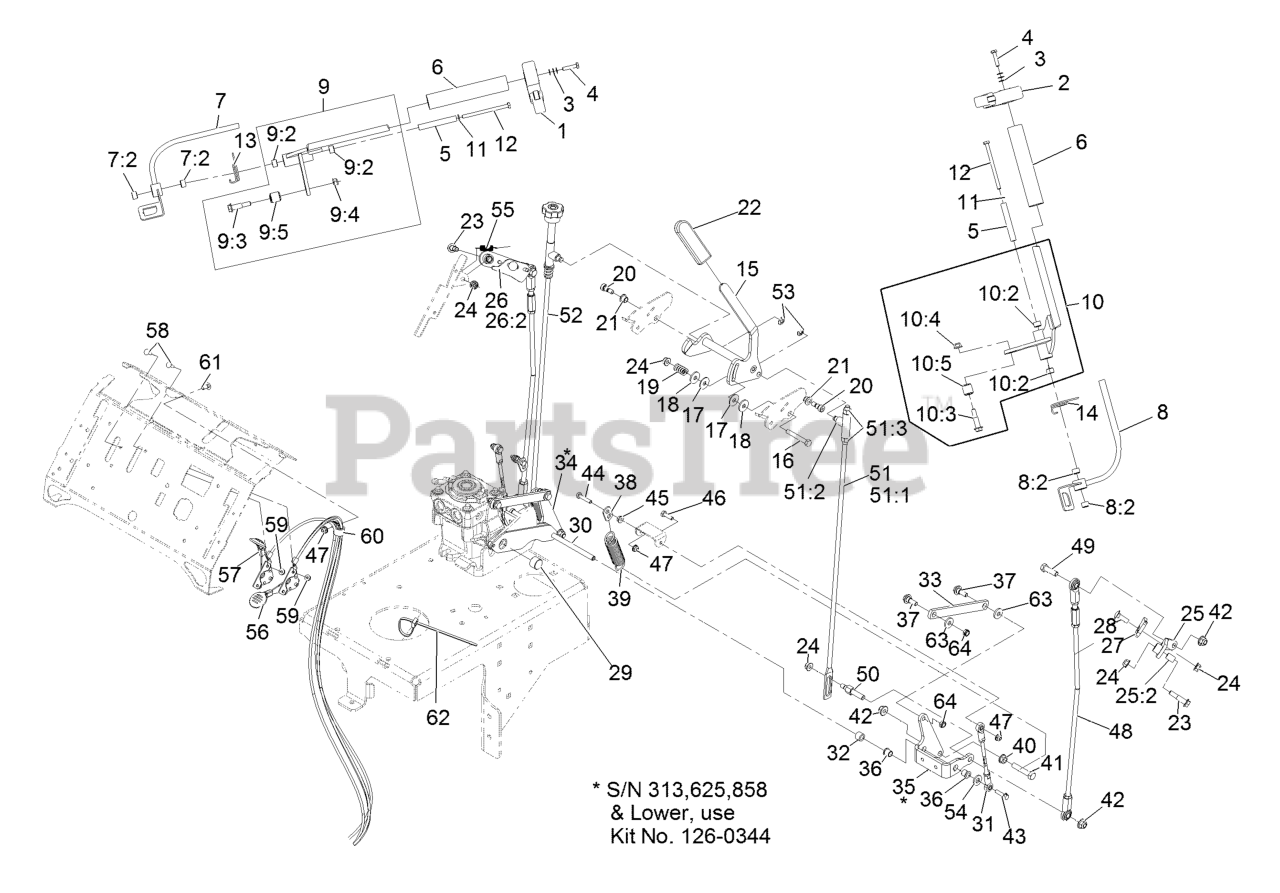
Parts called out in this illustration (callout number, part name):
1	ASM,LATCH RH THUMB
2	ASM,LATCH LH THUMB
3	WASHER-SPRING
4	SCREW-HH
6	GRIP-BAR, HANDLE
7	OPC-W/BUSHING, RH
7:2	BUSHING-SLEEVE
8	OPC-W/BUSHING, LH
8:2	BUSHING-SLEEVE
9	ASM, CONTROL-RH
9:2	BUSHING-SLEEVE
9:3	SCREW-SHOULDER
9:4	NUT-HF, NI
9:5	ASM, ROLLER
10	ASM, CONTROL
10:2	BUSHING-SLEEVE
10:3	SCREW-SHOULDER
10:4	NUT-HF, NI
10:5	ASM, ROLLER
11	SCREW-HH
12	SCREW-HH
13	SPRING, TORSION
14	SPRING, TORSION
15	SPEED CONTROL ASM
16	SCREW-HH
17	WASHER-FRICTION
18	WASHER-FRICTION
19	SPRING-COMPRESSION
20	SCREW-HSH
21	BUSHING
22	GRIP-HANDLE, STEERING
23	SCREW-SHOULDER
24	NUT-HF, NI
25	ARM ASM-LEFT
25:2	SLEEVE-BEARING
26	ARM ASM -RIGHT
26:2	SLEEVE-BEARING
28	BOLT-CARR
29	PIN-BELLCRANK LINK RETAIN
30	BELLCRANK LINK ASM
31	ASM, LINK
32	SPACER-WHEEL
33	LINK-BELLCRANK, PUMP
34	BELLCRANK-LOWER, RT
35	BELLCRANK-LOWER, LT
36	BEARING
37	SCREW-SHOULDER
38	ANCHOR, SPRING
39	SPRING-EXTENSION
40	NUT-HHF, WHIZ
41	SCREW-HH
42	NUT-HF, NI
43	SCREW-HHF
44	SCREW-HH
46	SCREW-HH
48	ASM, ROD
49	SCREW-HH
50	STUD-CONTROL, SPEED
51	ASM, ROD LEFT
51:1	ROD, LEFT
51:3	NUT-HEX
52	ASM, ROD RIGHT
53	RING-RETAINING
54	WASHER-FRICTION
55	SPRING-EXTENSION
56	CONTROL-THROTTLE
57	CONTROL-CHOKE
58	BOLT-CARR
59	NUT-LOCK, FLANGE
60	CLAMP-CABLE
61	SCREW-CARR
62	TIE-CABLE
63	WASHER-FLAT
64	NUT-LOCK, NI
